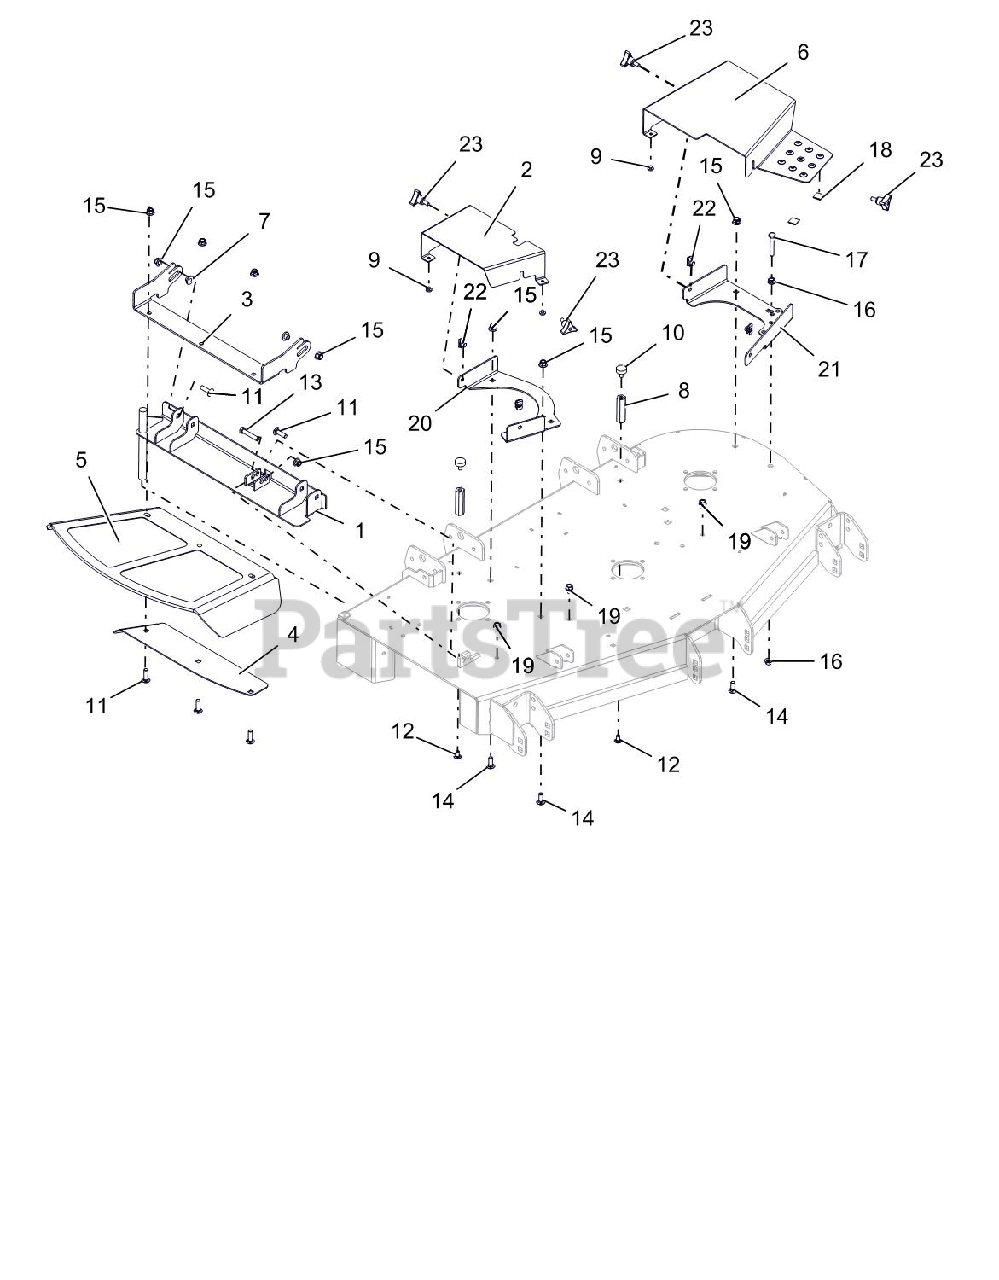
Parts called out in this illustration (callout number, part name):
1	48-60 DISCH CHUTE MTG W/SAFETY DECAL
2	GUARD, PT148-152 DECK RH BELT (RED)
3	BRKT, 48-60" CHUTE MTG (RED)
4	PLATE, 48-60" DISCH CHUTE CLAMP (RED)
5	CHUTE, 48-60" FORMED RUBBER DISCHARGE
6	GUARD, PT100 DECK LH BELT (RED)
7	BSHG, FLG .385 X .500 X .875 X .406
8	NUT, COUPLING
9	BUMPER, GROMMET
10	BUMPER, RUBBER
11	BLT-RHDSSQNK .38-16X1.25 G5YZ
12	BLT-RHDSSQNK .31-18X.62 G5YZ LOCKING
13	BOLT, HEX 0.375-16X2 GR5
14	BOLT, CARRIAGE 0.375-16X1 GR5
15	NUT-LK-NYL-FLG .38-16 YWZC
16	@NUT-SPNLK-FLG .375-16 YWZC
17	BOLT, HEX 0.375-16X2.25 GR5
19	SCR-TAP .38-16X.50 HWH TR YWZ
20	BRKT, BELT GUARD RH MOUNTING (RED)
21	BRKT, BELT GUARD LH (RED)
22	NUT-CLIP RETAINER 5/16-18X.56
23	KNOB, WING STUD .312-18X.75
